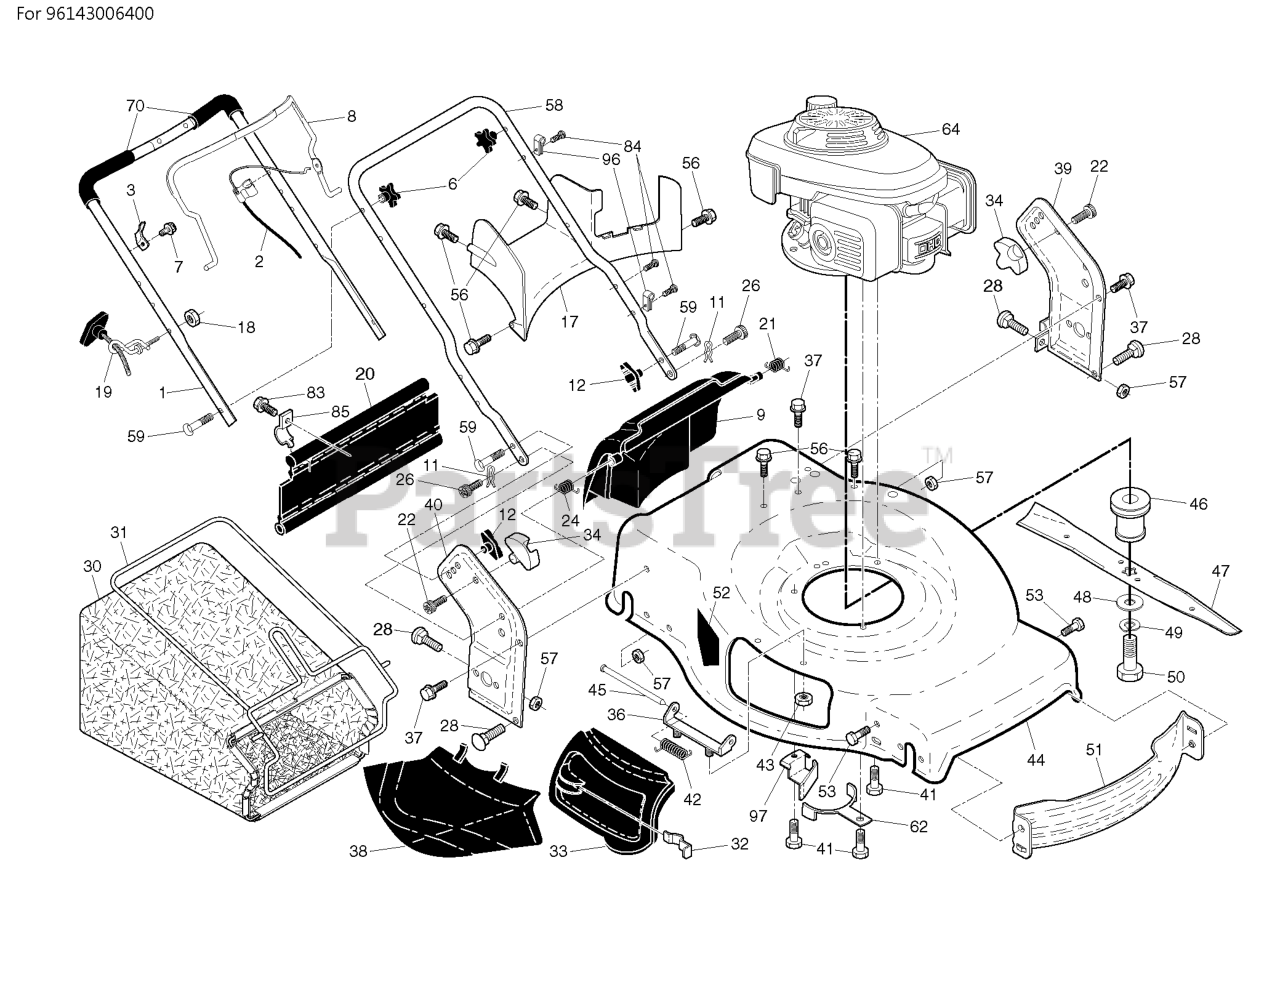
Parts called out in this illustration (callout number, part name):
1	HANDLE.ASM.UPPER.W/GRIP
2	CABLE.MZR.RGD.PLUS.ERG
3	BRACKET.UPSTOP.RT
6	KNOB.HANDLE.PLASTIC.STAR.BLACK
8	BAIL.CONTROL.MZR.BS.ORANGE
9	DOOR.REAR.ASM.22+.HUSQ.FG/RGD
11	COTTER.HAIRPIN.DOOR/HANDLE.PIV
12	KNOB, DEFLECTOR
17	RP.BAFFLE.REAR.22+.RGD.PL
18	NUT
19	RB GUIDE.ROPE.STD.BLK.ZIN WSL
20	SKIRT.REAR.22PLUS.RGD/FGD.NEW
21	SPRING.LH.BLACK
22	SCREW.PAN.HEAD.#10
24	SPRING.RH.GRAY
26	SCREW,DOOR/HANDLE.PIVOT
28	BOLT
31	RB FRAME.GBAG.22PLUS
32	Latch, Mulcher Door
33	DOOR.ASM.MULCH.22.PLUS
34	BRACKET.GRASSBAG.ATTAC
36	BRACKET.ASM.HINGE.21.FWGD.
37	BOLT.HEX.HD.WASHER.5/16-18X.75
38	DEFLECTOR.CLIPPING.22.BLACK
39	BRACKET.ASM.HANDLE.LT.22+.FG
40	BRACKET.ASM.HANDLE.RT.22+.FG
41	BOLT 3/8-16X1-1/8
42	SPRING.TORSION
43	NUT.HEX.FLANGE.1/4
44	KIT.HSG.22+RGD.MC.WO.ORG.CESYM
45	ROD.HINGE.21
46	ADPTER.BLAD.25M.VS.22PLU.STAR
47	BLADE.22PLUS
48	WASHER,HARDEN
49	LOCKWASHER
50	SCREW, HEX HD 3/8-24 X 1-3/8
51	BAFFLE.FRONT.22.PLUS
52	DANGER DECAL
53	BOLT.5/16HEX.WHS.HD
56	SCREW.HX.13X.750
57	NUT.FLANGE.5/16
58	HANDLE.LOWER.22+.BLACK
59	BOLT, HANDLE 5/16-18X1.75
62	BRACKET.KEEPER.BELT
70	GRIP.HANDLE.FOAM.WIDE.(1 SIDE)
83	TAPPING SCREW
84	FASTENER.PUSH.O.250X0.783
85	BRACKET.SKIRT.22+.BZP
96	CLIP.CABLE.BLK
97	BRACKE.BELT.GUIDE.22+
